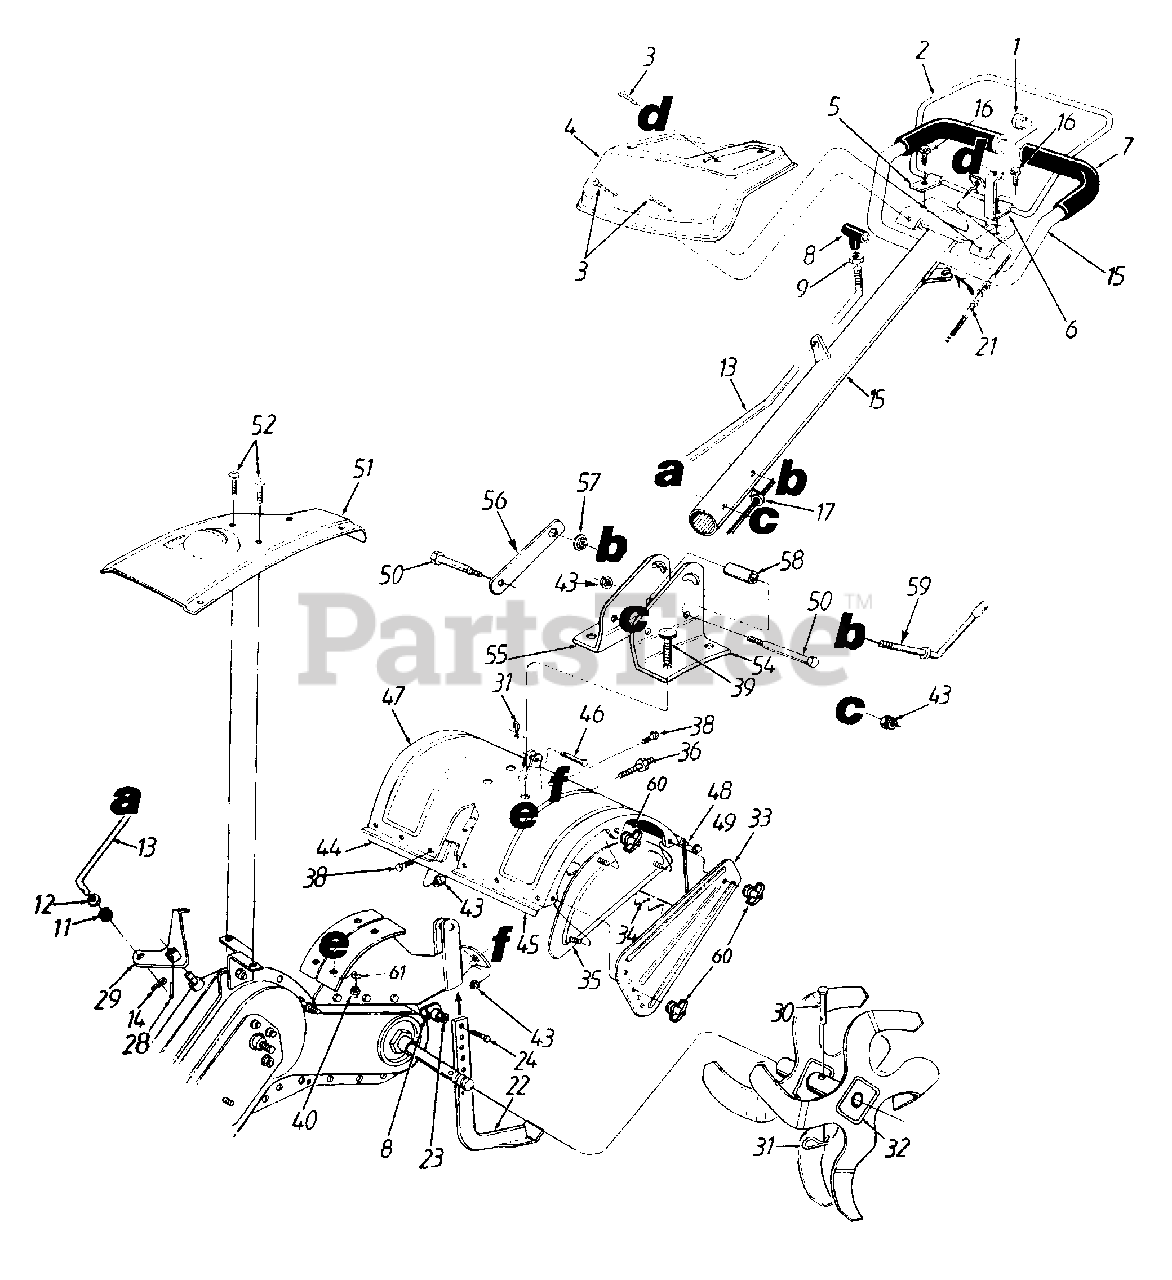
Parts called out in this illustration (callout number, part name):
1	Vinyl End Plug
3	Torx Mach. AB-Tap Scr. 1/4 x .62" Lg.
7	Grip (2 Req'd.)
9	Hex Jam Nut 3/8-16 Thd.
11	Rubber Washer
12	Fl-Wash. .344" I.D. x .6" O.D.
13	Gear Shift Rod
14	Hairpin Clip
17	Cable Clip
21	Clutch Cable
23	Fl-Wash. 3/8" I.D. x 5/8" O.D.
24	Hex Bolt 3/8-16 x 1" Lg.
28	Spiral Pin 3/16" x 1"
31	Hairpin Clip
36	Hex Cap Bolt 5/16-18 x 1.25"
38	Hex Bolt 5/16-18 x .75" Lg.
39	Carriage Bolt 3/8-16 x 1" Lg.
40	Hex Ins. L-Nut 3/8-16 Thd.
43	Hex Flange Top L-Nut 5/16-18 Thd.
46	Clevis Pin .375" Dia.
49	Cap Speed Nut
50	Hex Bolt 5/16-18 x 3" Lg.
57	Hex Flange Nut 3/8-24 Thd.
58	Spacer .322 Dia.
59	Handle Adjustment Crank
60	Knob 5/16-18 Thd.
61	L-Washer 3/8" I.D.
